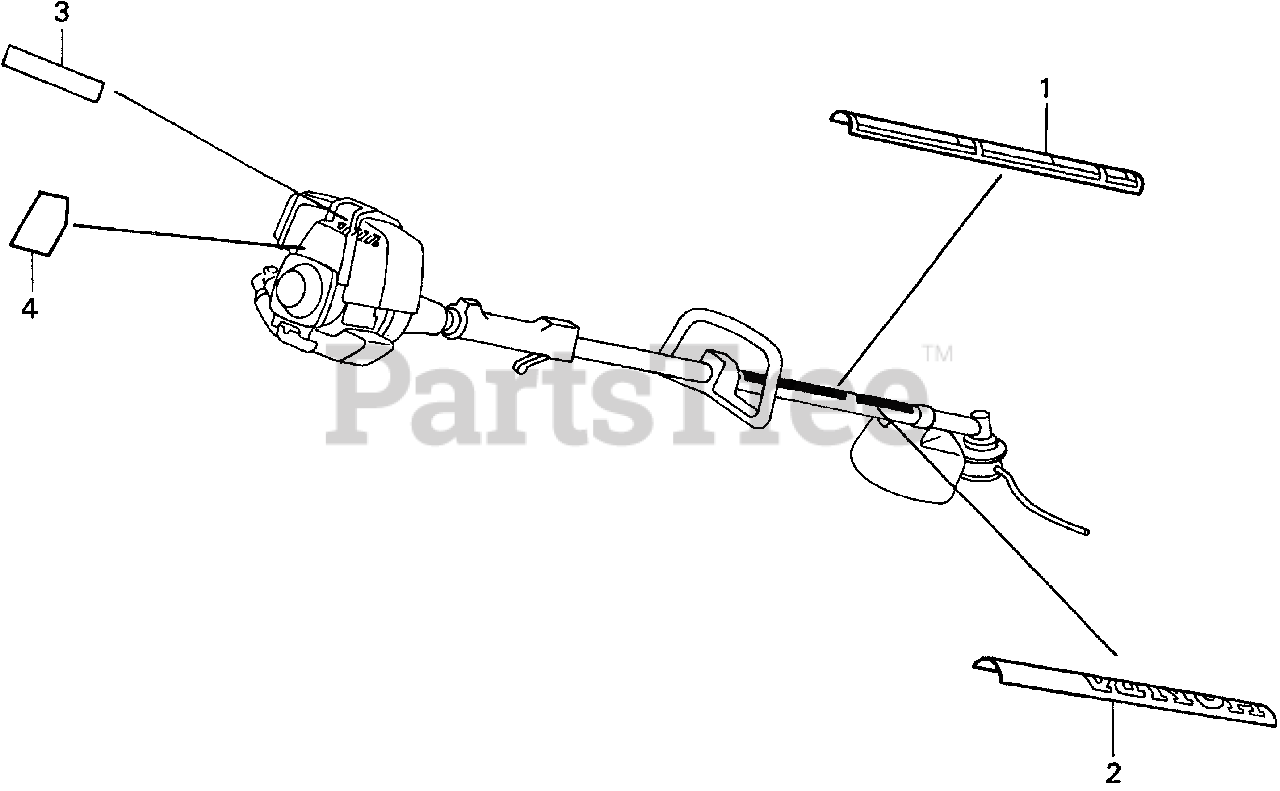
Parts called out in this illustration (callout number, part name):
1	MARK, CAUTION
2	MARK, EMBLEM (UMK431)
2	EMBLEM (UMK431)
3	MARK, HONDA
4	MARK, OIL CAUTION
4	MARK, OIL CAUTION (ENGLISH)
